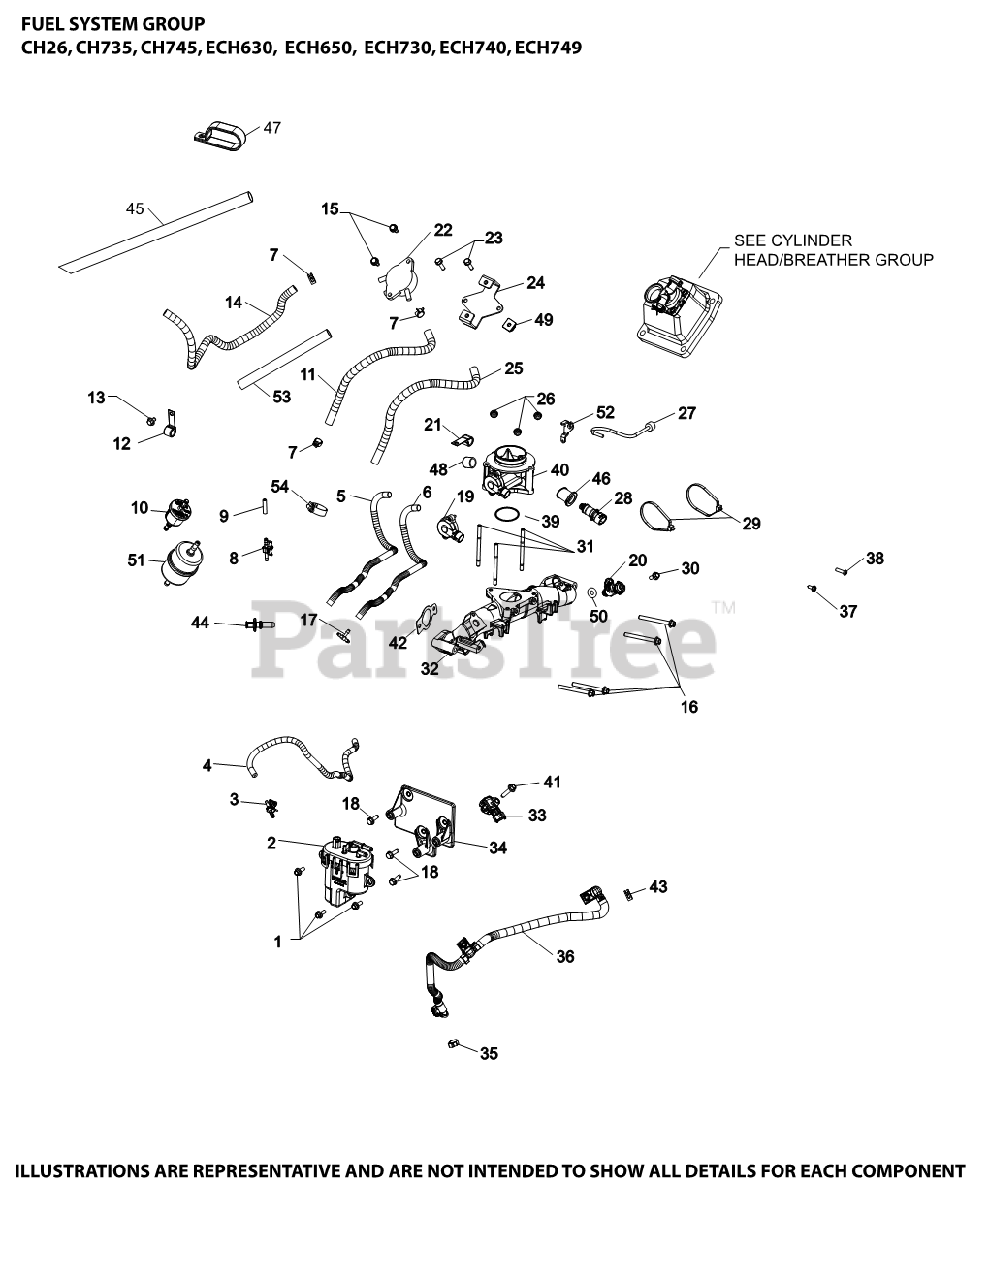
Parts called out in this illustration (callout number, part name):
1	SCREW, FLG M6X1.0X16
2	PUMP, FUEL MODULE
4	HOSE, EVAPORATIVE (15.0)
5	SLEEVE, ANTI-ABRASION
7	CLAMP, HOSE (KM)-USE 25 237 31-S
8	SCREW, FLG M6x1.0x20
11	HOSE,LW PERM.FUEL 24.00"-USE 25 111 81-S
16	SCREW, FLG M6X1.0X60
17	TEE CONNECTOR
18	SCREW, THREAD FORMING
19	SENSOR, THROTTLE POSITION
20	INJECTOR, FUEL
21	CLIP, CABLE
31	STUD,M6X1.0X84
32	KIT, MANIFOLD
33	SENSOR, T-MAP
34	BAFFLE, FUEL MODULE
35	CLAMP, HOSE
36	RAIL, FUEL ASSEMBLY (HORIZONTAL COMMAND)
40	BODY, THROTTLE ASM W/ PIN (30)
42	GASKET, INTAKE MANIFOLD USE 24 041 79-S
43	CLAMP, OETIKER
48	CAP, MASKING
50	KIT, FUEL INJECTOR O-RING
55	SLEEVE, ANTI ABRASION -USE 25 431 12-S
63	MAGNET ASSEMBLY, TPS
64	O-RING, TPS SENSOR
65	CLIP, RETAINER
